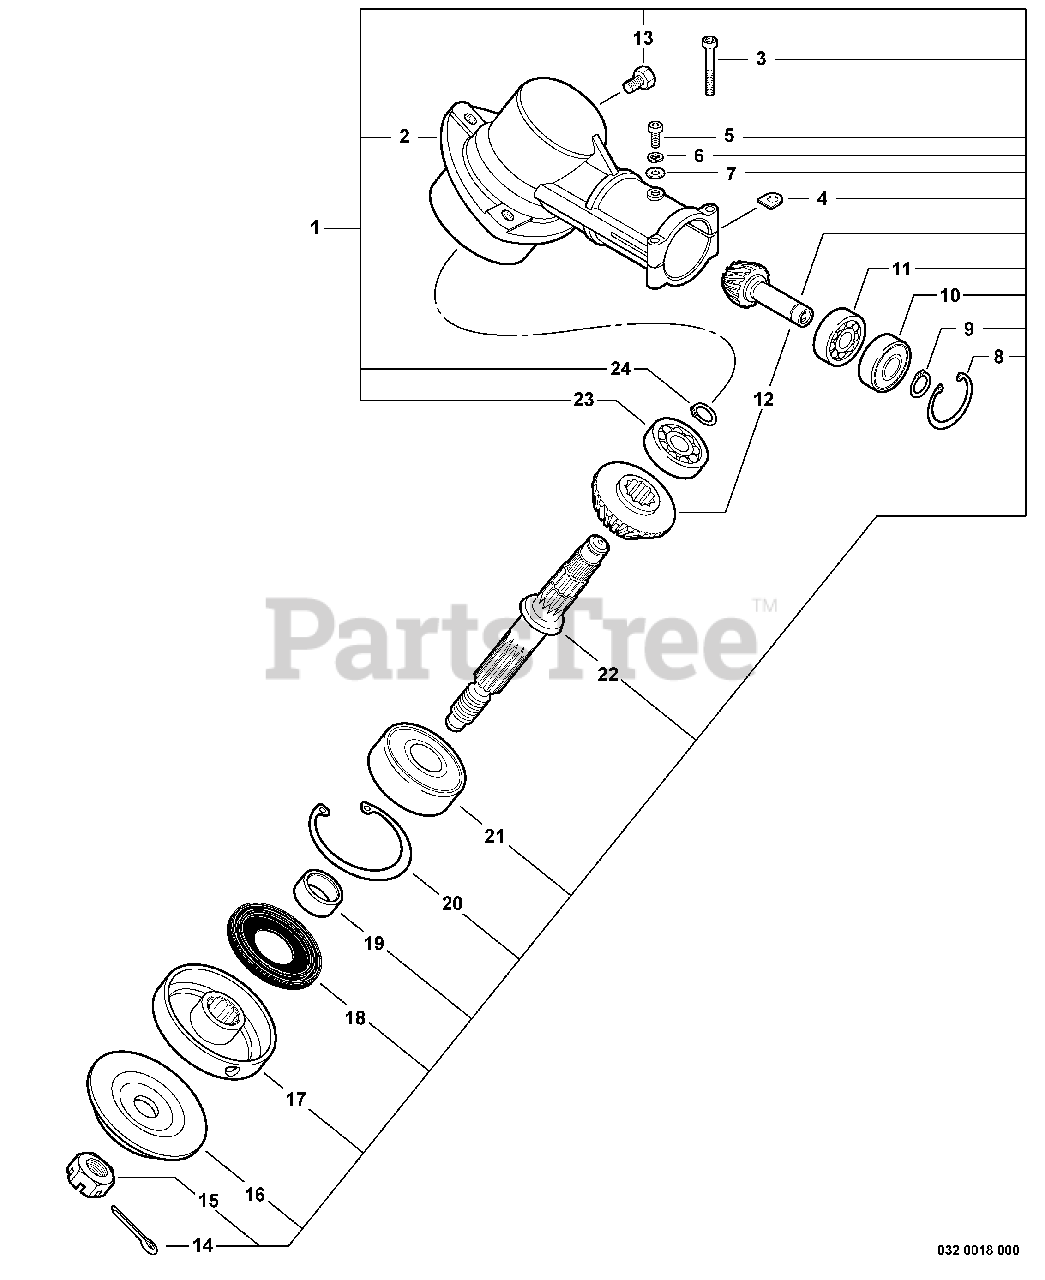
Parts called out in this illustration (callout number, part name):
1	GEAR CASE ASSY
2	HOUSING, GEAR CASE
3	BOLT, TORX 5×25
5	BOLT, TORX 5×12
6	WASHER, SPRING 5
7	WASHER, FLAT 5.5×10×0.8
8	RING, SNAP Ø22
9	RING, SNAP Ø10
10	BEARING, BALL 6900Z
11	BEARING, BALL 6900
12	GEAR SET
13	BOLT 8×8 SP
14	PIN, COTTER 2×22
15	NUT 10×1.25 LH
16	PLATE, ADAPTOR - LOWER
17	PLATE, ADAPTOR - UPPER
18	SEAL, OIL 22
19	SPACER 11.8×15×9
20	RING, SNAP Ø32
21	BEARING, BALL - 6201 C3
22	SHAFT, GEAR
23	BEARING, BALL 609
24	RING, SNAP Ø12
